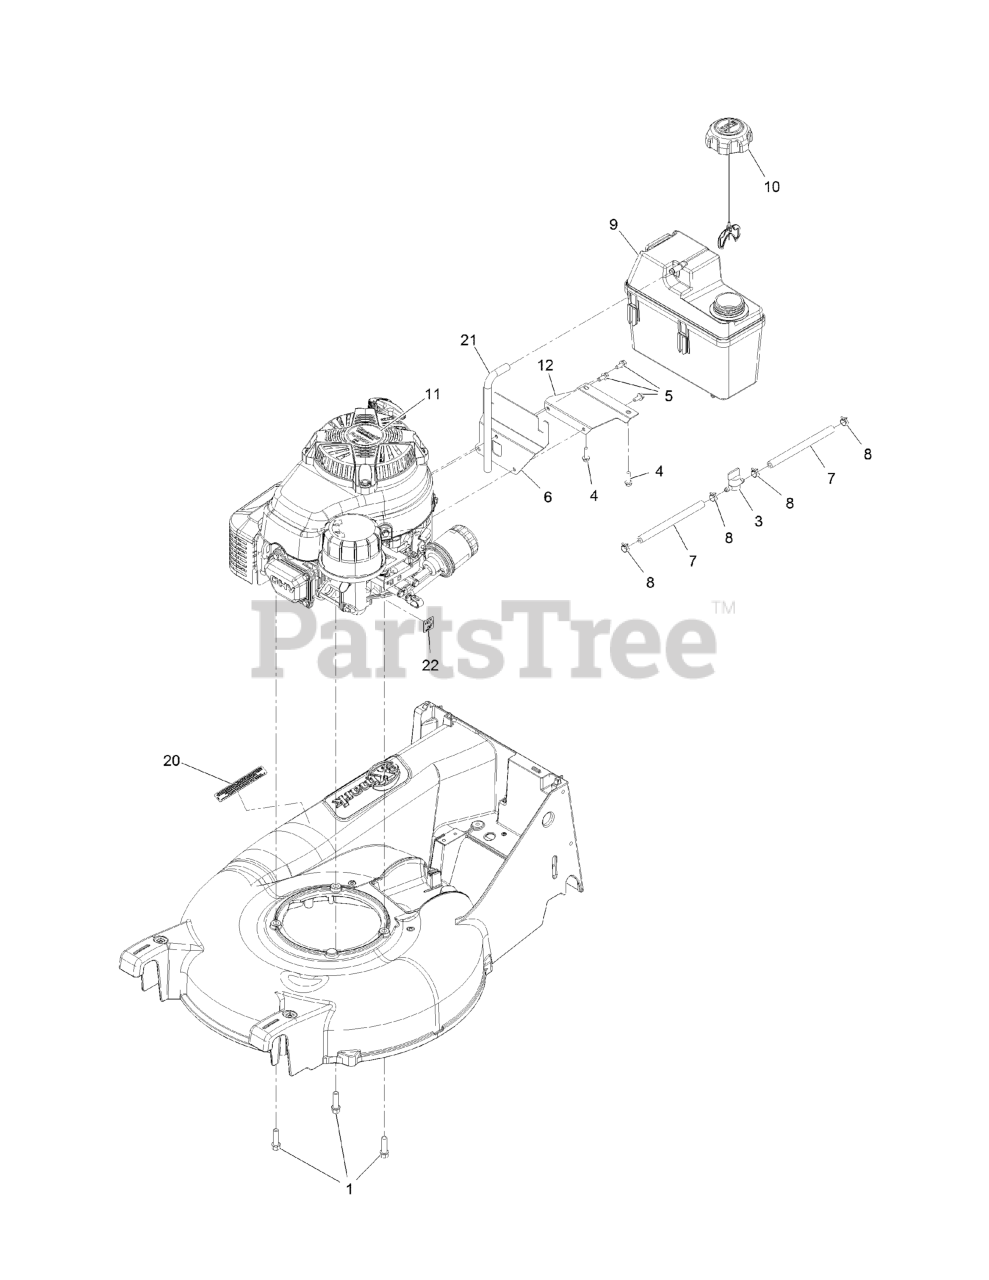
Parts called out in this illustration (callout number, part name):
1	SCREW-TAPTITE
3	VALVE-FUEL
4	SCREW-HWH
5	SCREW-HWH
6	BRACKET-TANK, MOUNTING
7	HOSE-FUEL
8	CLAMP-HOSE
9	TANK-FUEL
10	CAP-FUEL
12	BRACKET-TANK, SUPPORT
20	DECAL-ARRESTOR, SPARK
21	HOSE-VENT, CANISTER
22	DECAL-PRIMER
